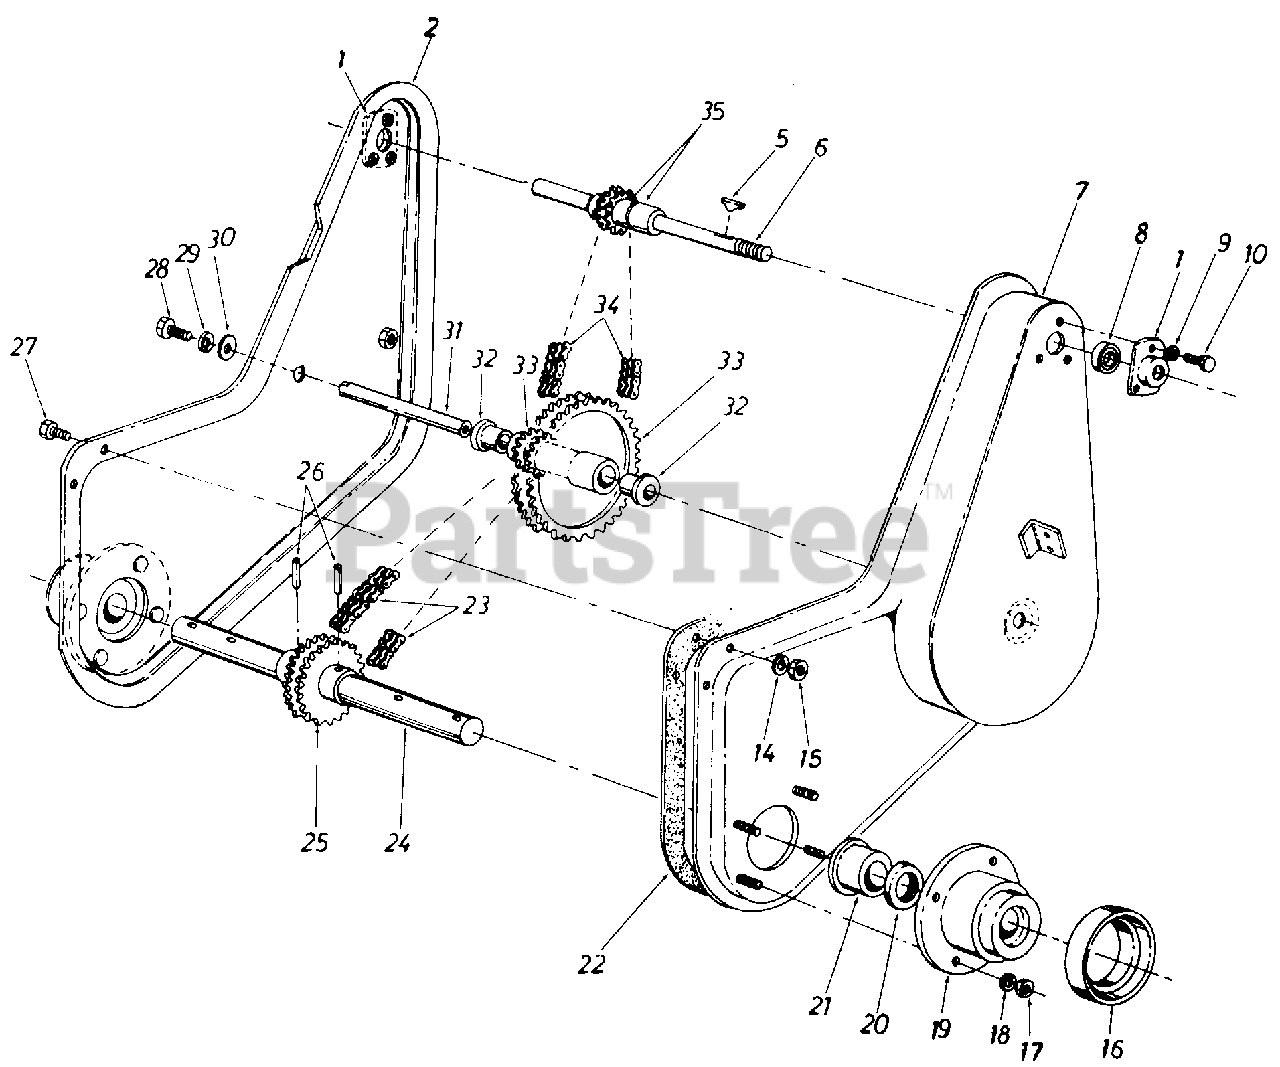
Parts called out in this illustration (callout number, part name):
1	Bearing Housing 1.375" Dia.
2	Housing Assembly R.H.
5	#6 Hi-Pro Key 5/32" x .62" Lg.
6	Input Shaft Assembly
9	L-Wash. 1/4" I.D.
10	Hex Bolt 1/4-20 x .62" Lg.
14	L-Wash. 1/4" I.D.
15	Hex Cent. L-Nut 1/4-20 Thd.
16	Dust Cap Cover
17	Hex Cent. L-Nut 5/16-18 Thd.
18	L-Wash. 5/16" I.D.
19	Cast Bearing Housing
20	Oil Seal
21	Flange Bearing 1.25" I.D. x 1.75" O.D.
22	Gasket
23	Roller Chain #40-2 x 34.0" Lg.
24	Tine Shaft
25	Double Sprocket T24-2 Teeth 1/2" Pitch
26	Spiral Pin 3/8" Dia. x 2.00" Lg.
27	-Hex Bolt 1/4-20 x .62" Lg.
28	Hex Bolt 5/16-18 x .75" Lg.
29	L-Wash. 5/16" I.D.
30	Fl-Wash. 5/6" I.D.
31	Sprocket Shaft
32	Flange Bearing .62" I.D. x .75" O.D.
33	Double Sprocket Assembly
34	Roller Chain #35-2 x 36.75" Lg.
35	Spacer 5/8" I.D. x 7/8" O.D.
